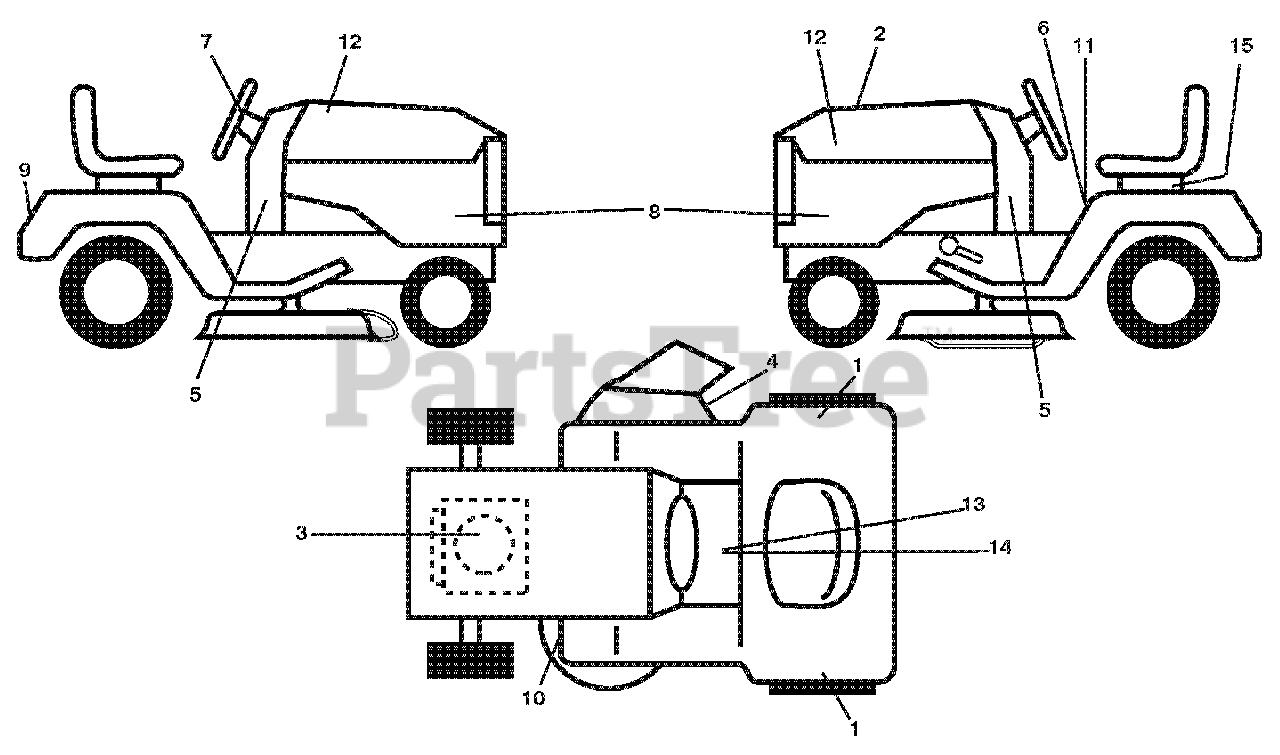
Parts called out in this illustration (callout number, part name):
1	DECAL.FENDER.SIDE.HYDRO
2	DECAL.REPLACEMENT
3	DECAL.ENGINE.HP
4	DECAL.WARNING.KEEP.HAND.AWY
5	DECAL.LOWER.DASH
6	DECAL.WARNING.START
7	DECAL.WHEEL.STEER.ARIENS
8	DECAL.SDPNL.PWRDBY B&S.ARIENS
9	DECAL.FENDER.REAR.ARIENS
10	DECAL.V-BELT.SCH.
11	DECAL.FENDER
12	DECAL.HOOD.LH/RH.
13	Decal, Spark Arrester
14	LABEL.EMISSIONS
15	DECAL.BAT.DAN/POI P/L SYM.WPN
